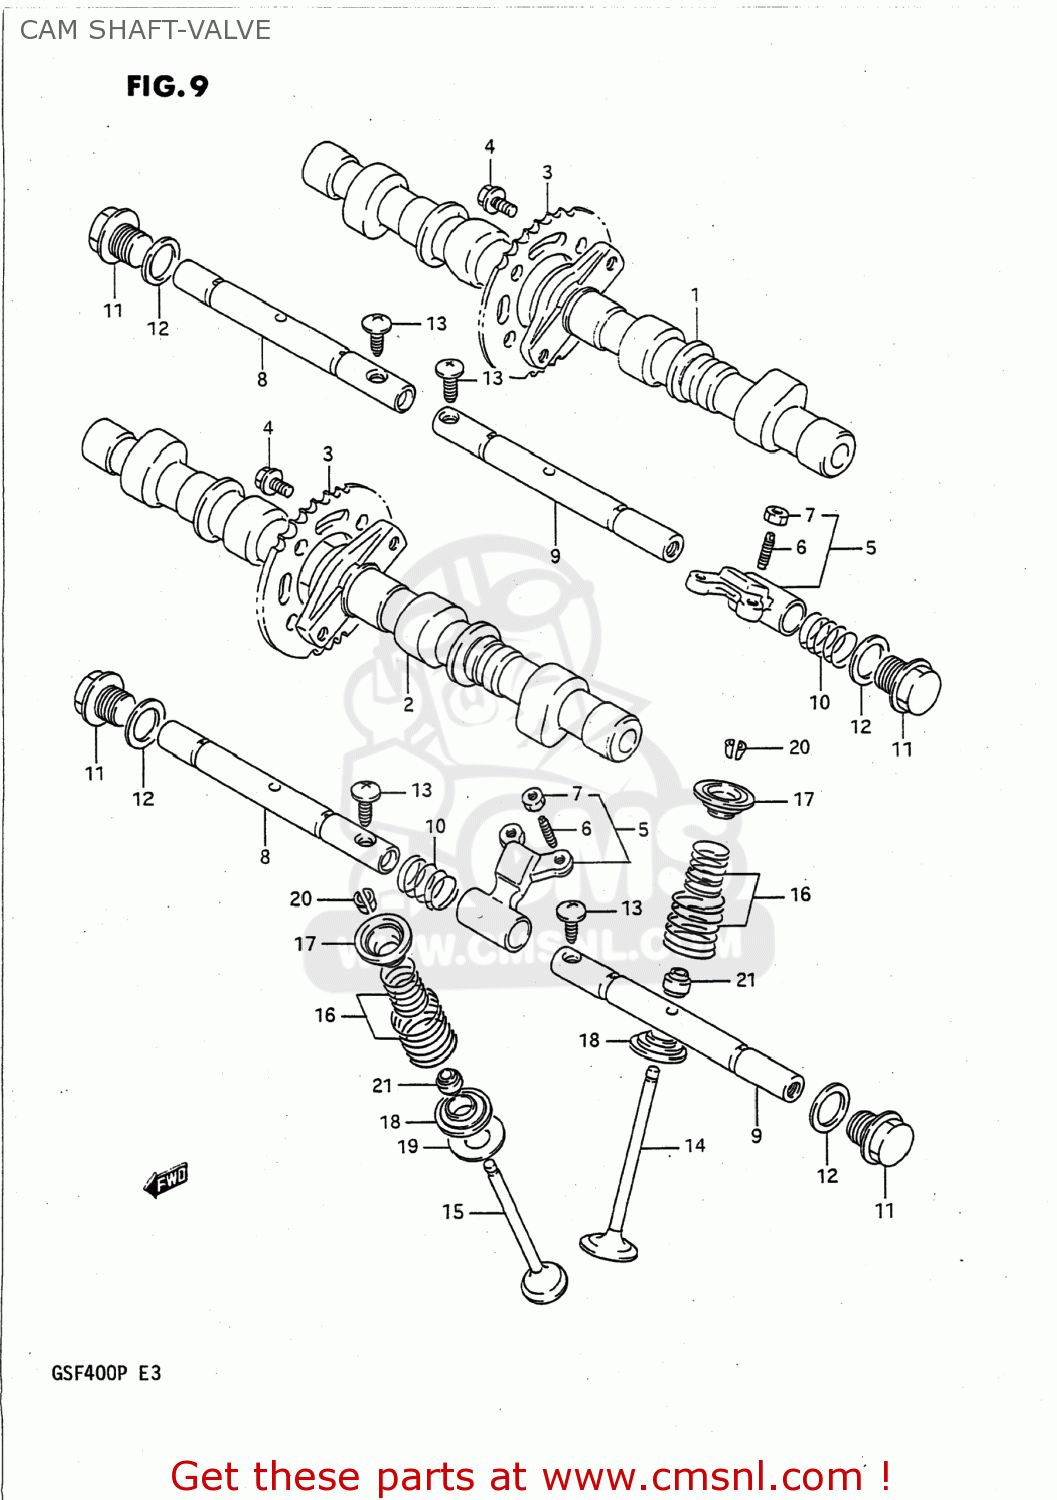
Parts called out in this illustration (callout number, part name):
1	CAMSHAFT,INTAKE
2	CAMSHAFT,EXHAUST
3	SPROCKET,CAMSHAFT
4	BOLT(7X10)
5	ARM,VALVE ROCKER
6	SCREW,TAPPET ADJUSTING
7	NUT,ADJUSTING
8	SHAFT,VALVE ROCKER ARM
9	SHAFT,VALVE ROCKER ARM
10	SPRING
11	PLUG
12	GASKET(14X19.2X2) (NAS)
13	SCREW(6X16)
14	VALVE,INTAKE
15	VALVE,EXHAUST
16	SPRING SET,VALVE
17	RETAINER,VALVE SPRING
18	SEAT,VALVE SPRING
19	SEAT,VALVE SPRING EXH OUTER
20	COTTER VALVE
21	SEAL,OIL(4.5X10X8)
